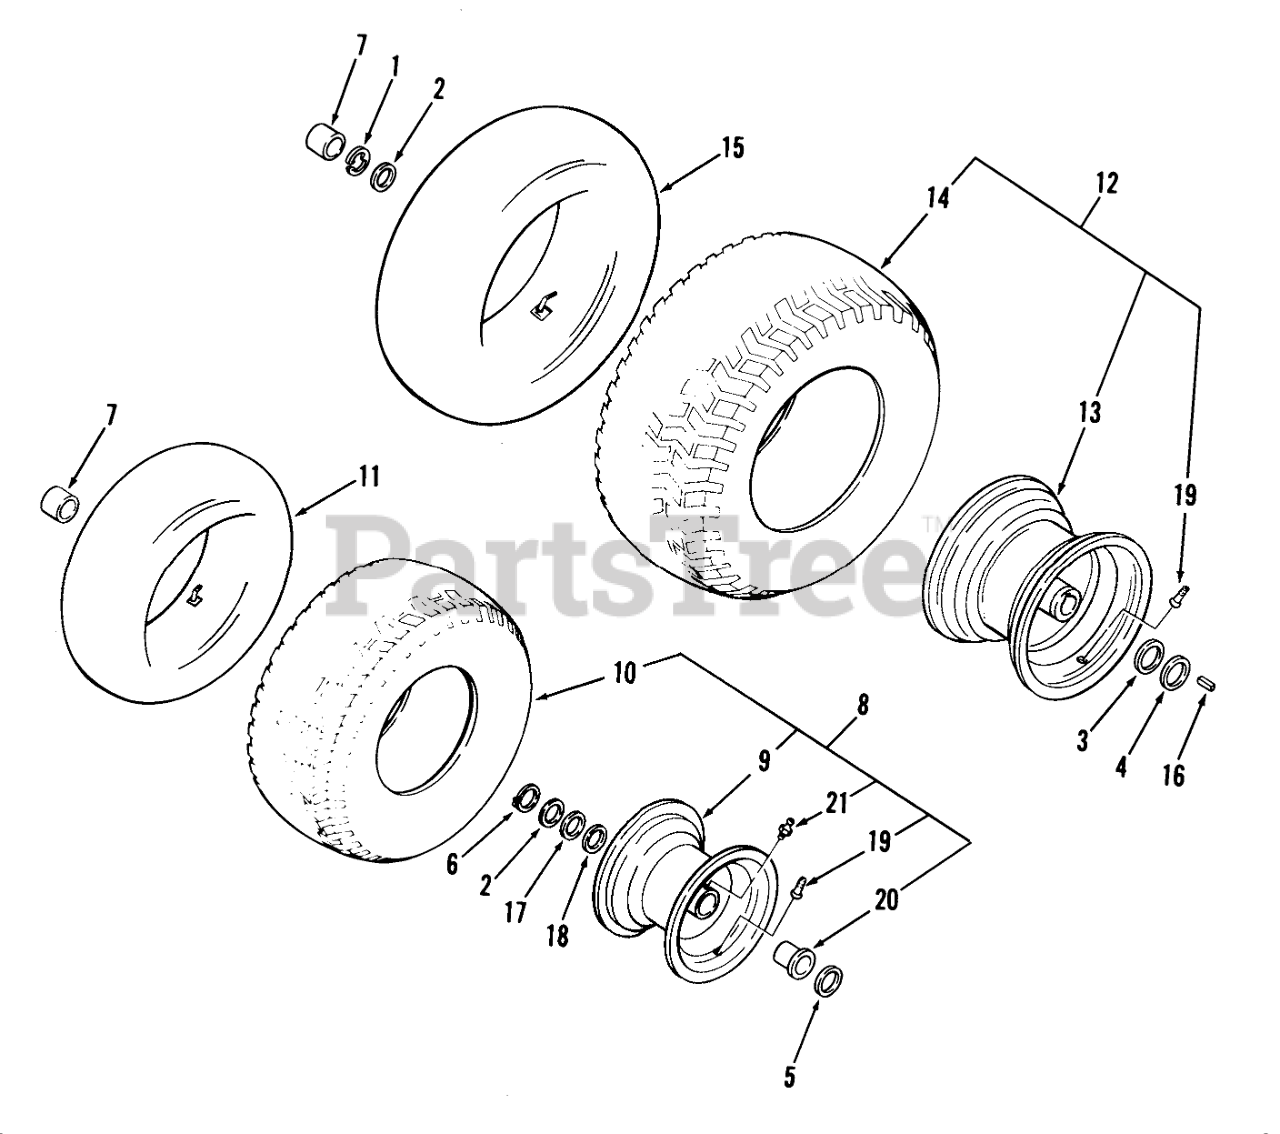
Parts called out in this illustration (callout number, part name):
1	E Ring
3	WASHER-SHIM
4	WASHER
5	Washer
6	Snap Ring
7	HUB CAP
8	Front Wheel
8	Wheel & Tire Assembly
9	Rim
9	ASSY-RIM
10	TIRE
11	Front Tube-Service Only
11	Tube (Service Only)
12	Assy-Wheel & Tire Rear
13	Rear Wheel
13	RIM ASSY
14	TIRE
14	Rear Tire 20 x 10.0-10.0
15	Rear Tube-Service Only
16	SQ KEY
17	WASHER
18	WASHER-SHIM
19	VALVE
20	FLANGE BEARING
21	Zerk
